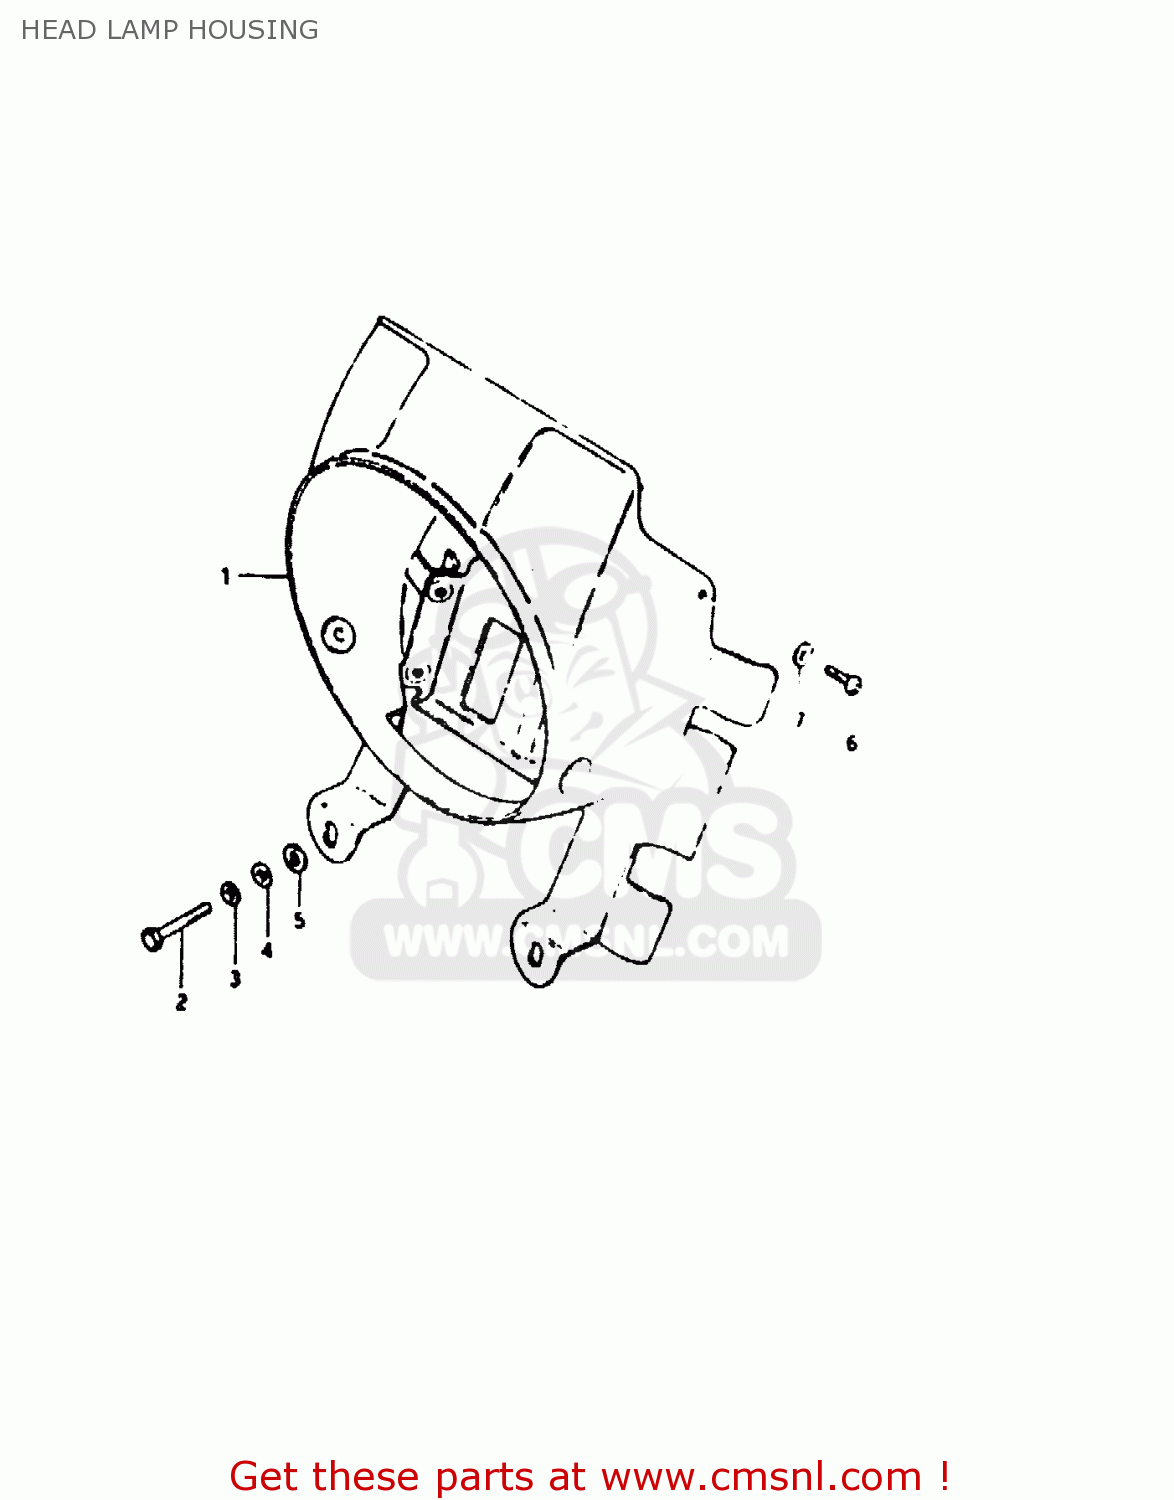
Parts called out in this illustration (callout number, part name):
1	HOUSING, HEADLAMP
2	BOLT
3	LOCK WASHER
4	WASHER
5	WASHER
6	SCREW
7	WASHER (5.5X16X1.2)
